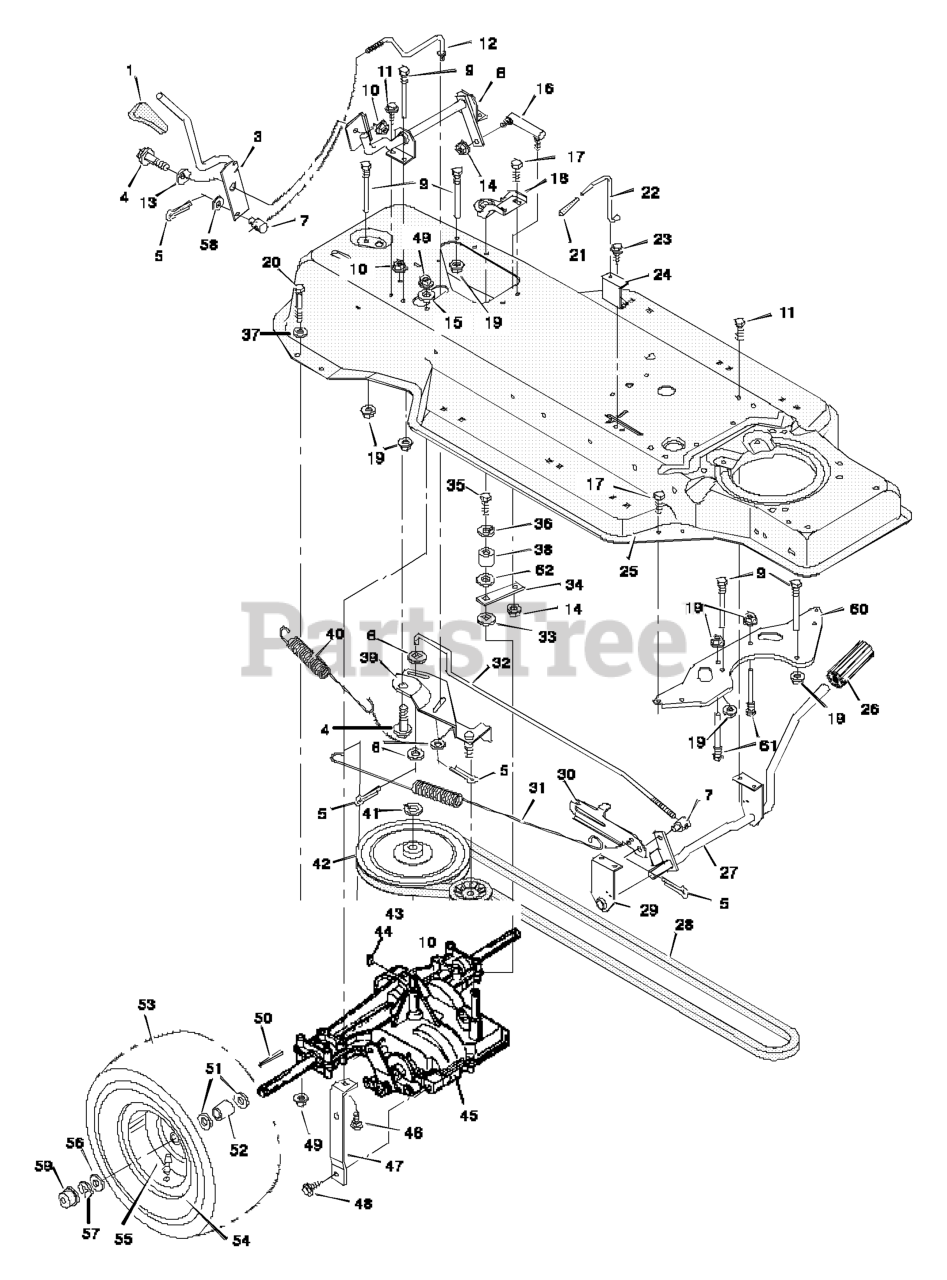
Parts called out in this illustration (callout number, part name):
1	Grip
3	Handle, Shift
4	Bolt, Shoulder
5	Pin, Cotter
6	Washer
7	Nut, Adjustable
8	Shifter Assembly
9	Guide, Belt
10	Locknut, Flange
12	Link, Clutch
13	Washer, Curved
14	Locknut, Flange
16	Link Assembly, Shifter
18	Bracket, Support
19	Nut, Flange
20	Bolt, Hex
22	Rod, Control
24	Guide, Bracket
25	Frame Assembly
26	Pedal, Clutch/Brake
27	Lever Assembly
28	Belt, Motion Drive
29	Bracket, Lever Support
30	Latch, Park Brake
31	Spring, Brake Extension
32	Rod, Clutch
34	Yoke, Shift
35	Bolt, Hex
36	Lockwasher
37	Washer
38	Pilot, Support
39	Bracket Assembly, Idler
40	Spring, Motion Drive
41	Ring, Retainer
42	Pulley, Motion Drive
43	Pulley, Backside Idler
44	Key, Woodruff
45	Transaxle, Peerless **
46	Bolt, Carriage
47	Support, Transaxle
49	Locknut, Flange
50	Key, Square
52	Spacer, Transaxle
53	Tire
54	Wheel and Tire Assembly
55	Valve Stem
57	E- Ring
58	Washer
59	Hub Cap
60	Plate, Belt Guide
61	Guide, Belt
